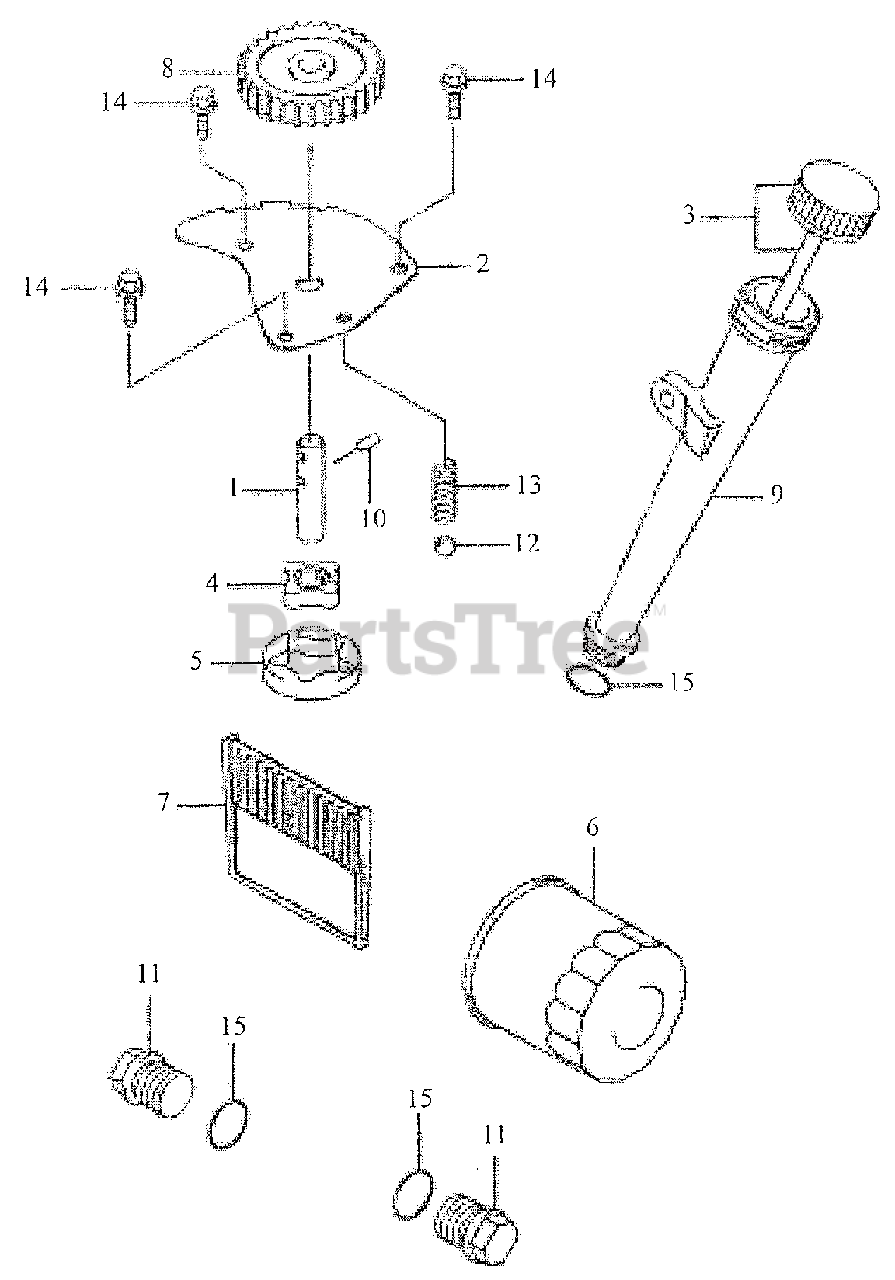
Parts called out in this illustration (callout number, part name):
1	Shaft, Oil Pump
3	Cap Assembly
4	Rotor, Pump In
5	Rotor, Pump Out
6	Filter, Oil
7	Filter, Oil
8	Gear, Spur
9	Filler Tube
10	Pin
11	Plug
14	Bolt, Flange
